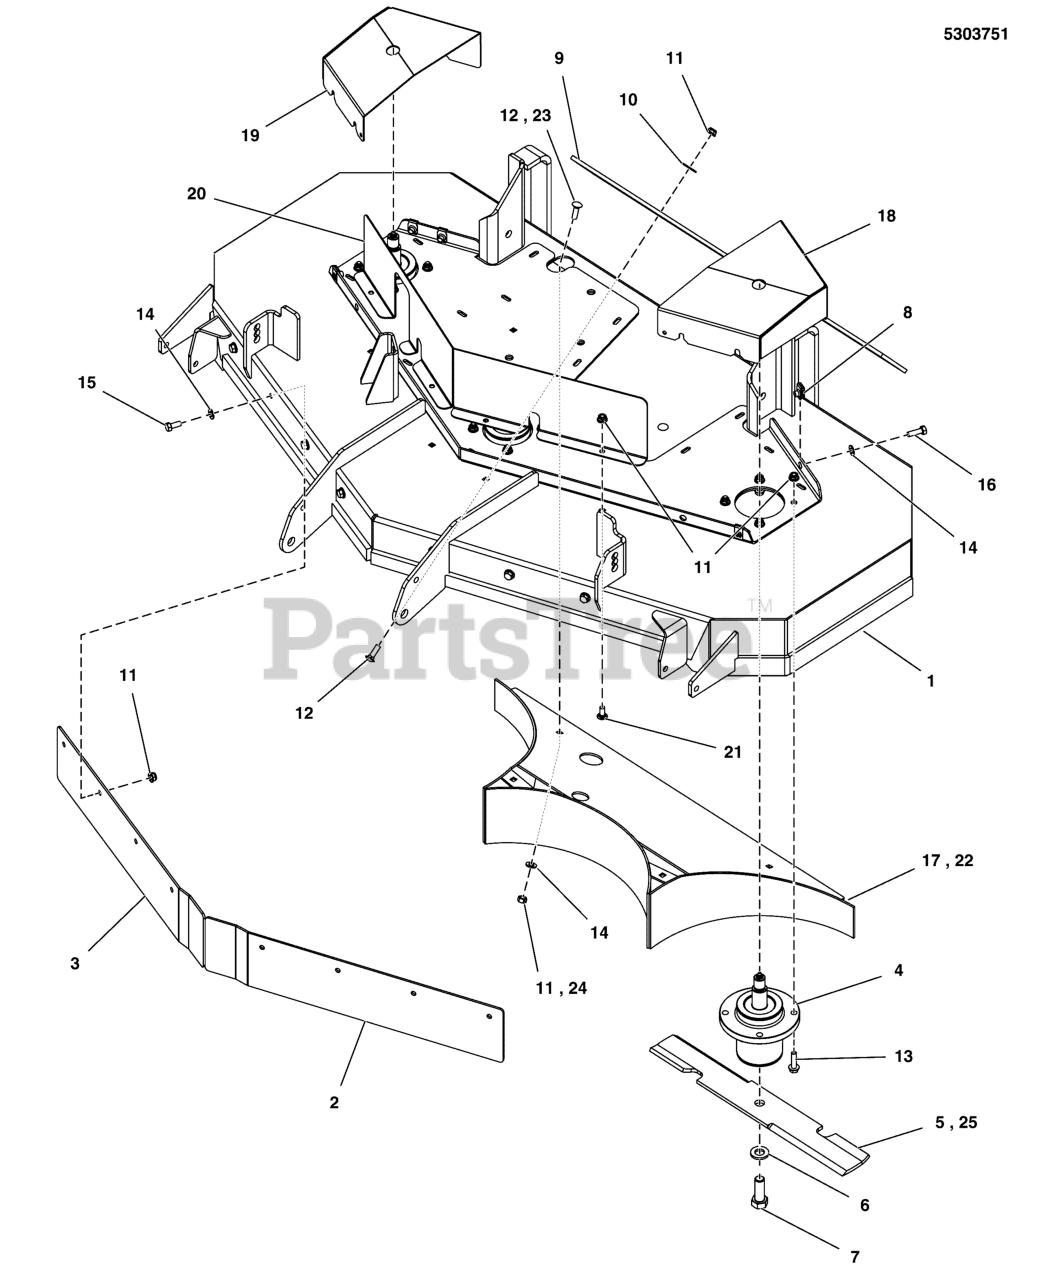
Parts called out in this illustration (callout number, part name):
1	DECK SHELL W/ DECALS, 52RDCE, FW35
2	BAFFLE, FRONT DISCHARGE, 52 LH CCW - RED
3	BAFFLE, FRONT DISCHAGE, 52 RH CCW - RED
4	ASSM, SPINDLE, LOW PROFILE
5	BLADE SET, SET OF THREE
6	WASHER, BLADE BOLT, 9/16" F436, CZ
7	BOLT, 5/8-11 X 1-3/4 GD8
8	BODY CLIP, 5/16-18-7GA MATERIAL
9	FLAP, CCW RD
10	WASHER, 5/16 FENDER
11	NUT, 5/16-18 HEX NYLOCK FLANGE
12	BOLT, 5/16-18 X 1, CARRIAGE
13	BOLT, 5/16-18 X 1 1/4 FLANGE
14	WASHER, 5/16" SAE
15	BOLT, 5/16-18 X 3/4 GD5
16	BOLT, 5/16-18 X 1 GD5 CZ
17	WELD, REAR BAFFLE, FW35 52 RD - RED
18	WELD, GUARD, FW35 52, LH - RED
19	WELD, GUARD, FW35 52, RH - RED
20	GUARD, FRONT DECK, FW35 52 RD - RED
21	BOLT, 5/16-18 X 3/4, CARRIAGE
22	WELD, REAR BAFFLE, WALK 52RD, SHORT, BLK
23	BOLT, 5/16-18 X 3/4, CARRIAGE
24	NUT, 5/16-18, HEX, CNTR LK,ZINC PHOS/OIL
25	BLADE SET, MULCH, 52 DECK (SET OF 3)
